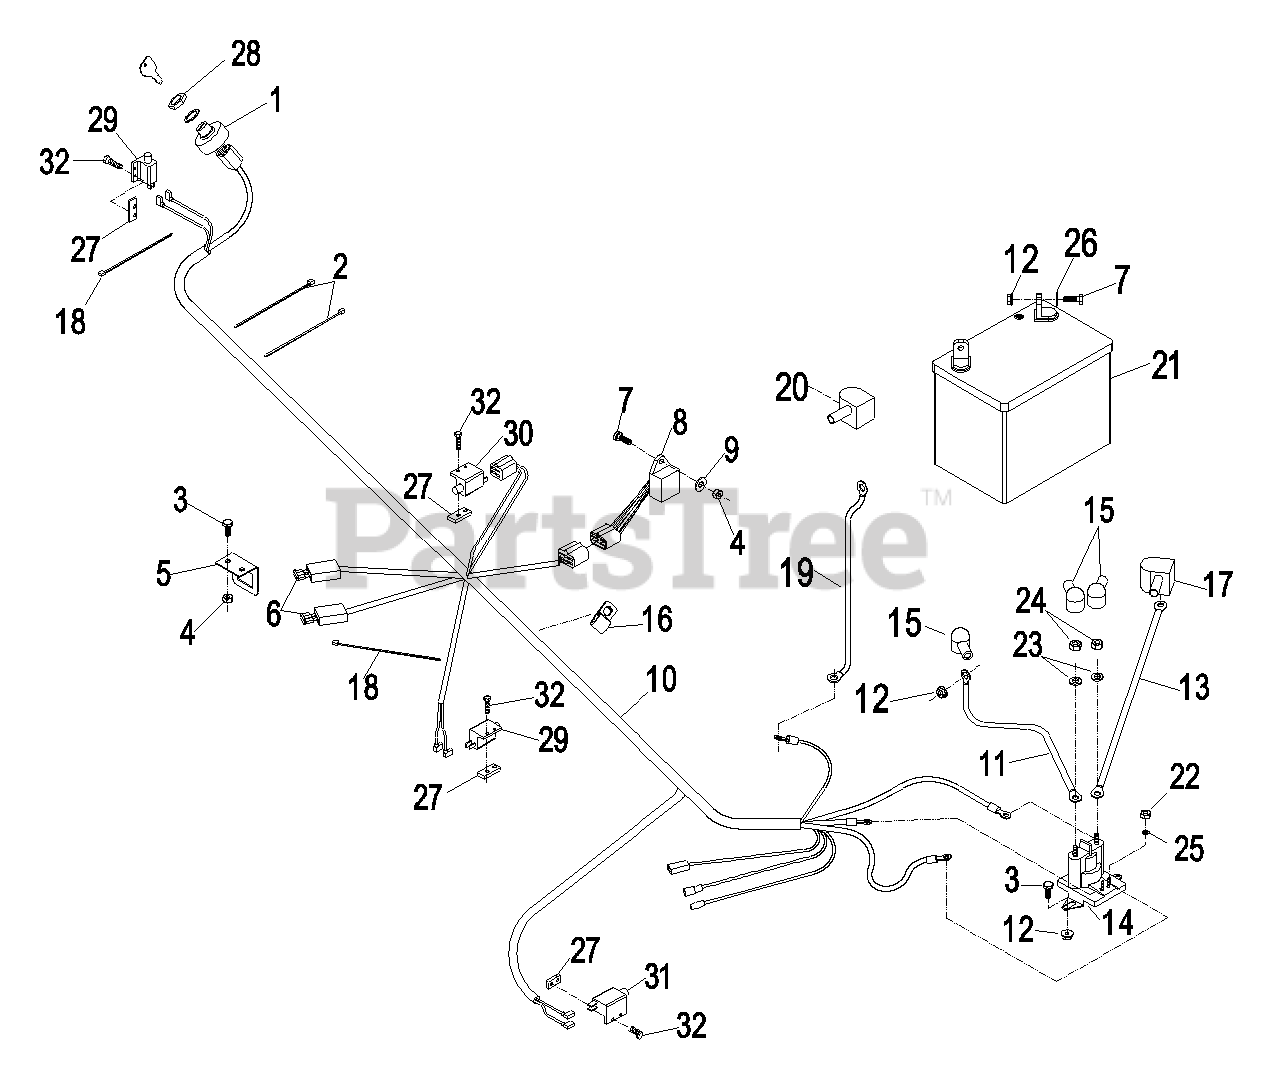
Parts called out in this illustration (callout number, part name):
1	SWITCH,IGNITION
2	TIE-PLASTIC
3	SCREW-HH
4	NUT-LOCK, NI
5	BRACKET,FUSE
6	FUSE-BLADE TYPE, 20 AMP
7	SCREW-HH
8	MODULE-OPC NO TIME DELAY
9	WASHER-FLAT
10	HARNESS,WIRING ELEC ST
15	INSULATOR-SOLENOID
16	CLIP-LOOM
18	TIE-CABLE
19	CABLE-BATTERY, NEGATIVE
20	INSULATOR, BATTERY -
22	NUT-HEX
23	WASHER-LOCK
24	NUT-JAM
25	WASHER-LOCK
26	WASHER-FLAT
27	PLATE-TAPPED
28	NUT-SWITCH, IGNITION
29	SWITCH-OPEN, NORMALLY
31	SWITCH-CLOSED, NORMALLY
32	SCREW-PPH
